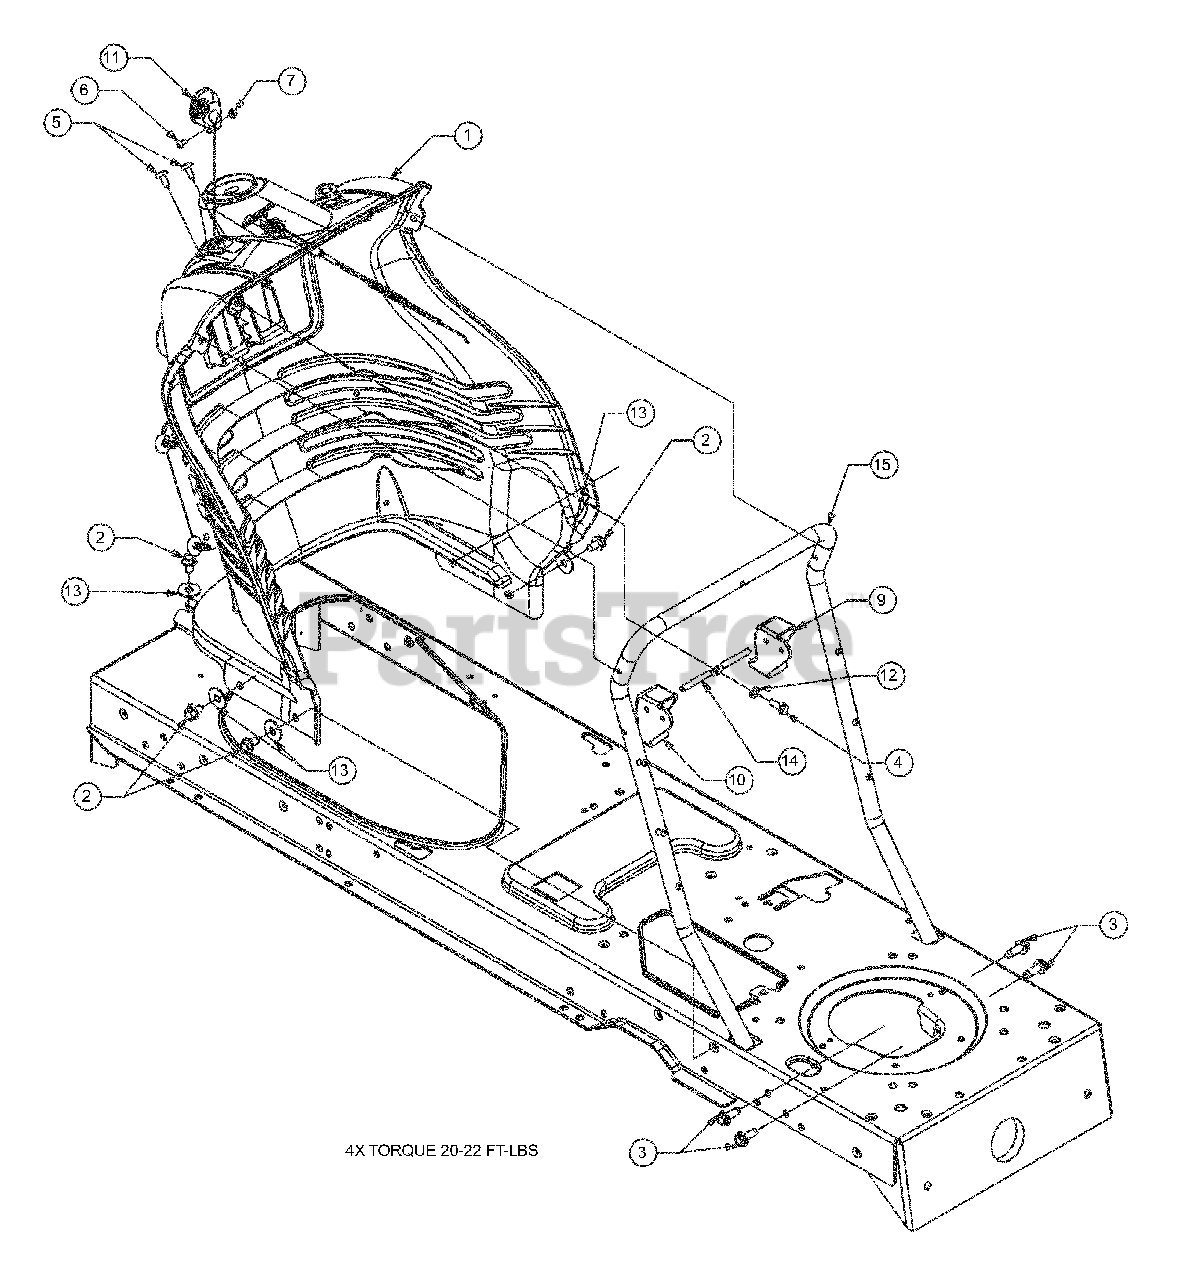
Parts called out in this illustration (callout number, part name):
1	DASH ASM:4 STYLE:CARGO NET
2	SCR:TT:5/16-18:0.625:HXINDWSH
3	SCR:TT:5/16-18:0.875:HXINDWSH
4	SCR:HL:1/4-15:0.750:HXINDWSH
5	SCR:AB:1/4-14:0.625:TRUSTRXI
6	SCR:MACH:#8-32:0.375:TRUSPHI
7	NUT:8-32:HEX MACH SCR:
9	LVR:DASH:BRAKE
10	LVR:DASH:CRUISE
12	WASH:FLAT:.281 X .50 X .063
13	FL-WASH .344 X 1.00 X .063 HDN
